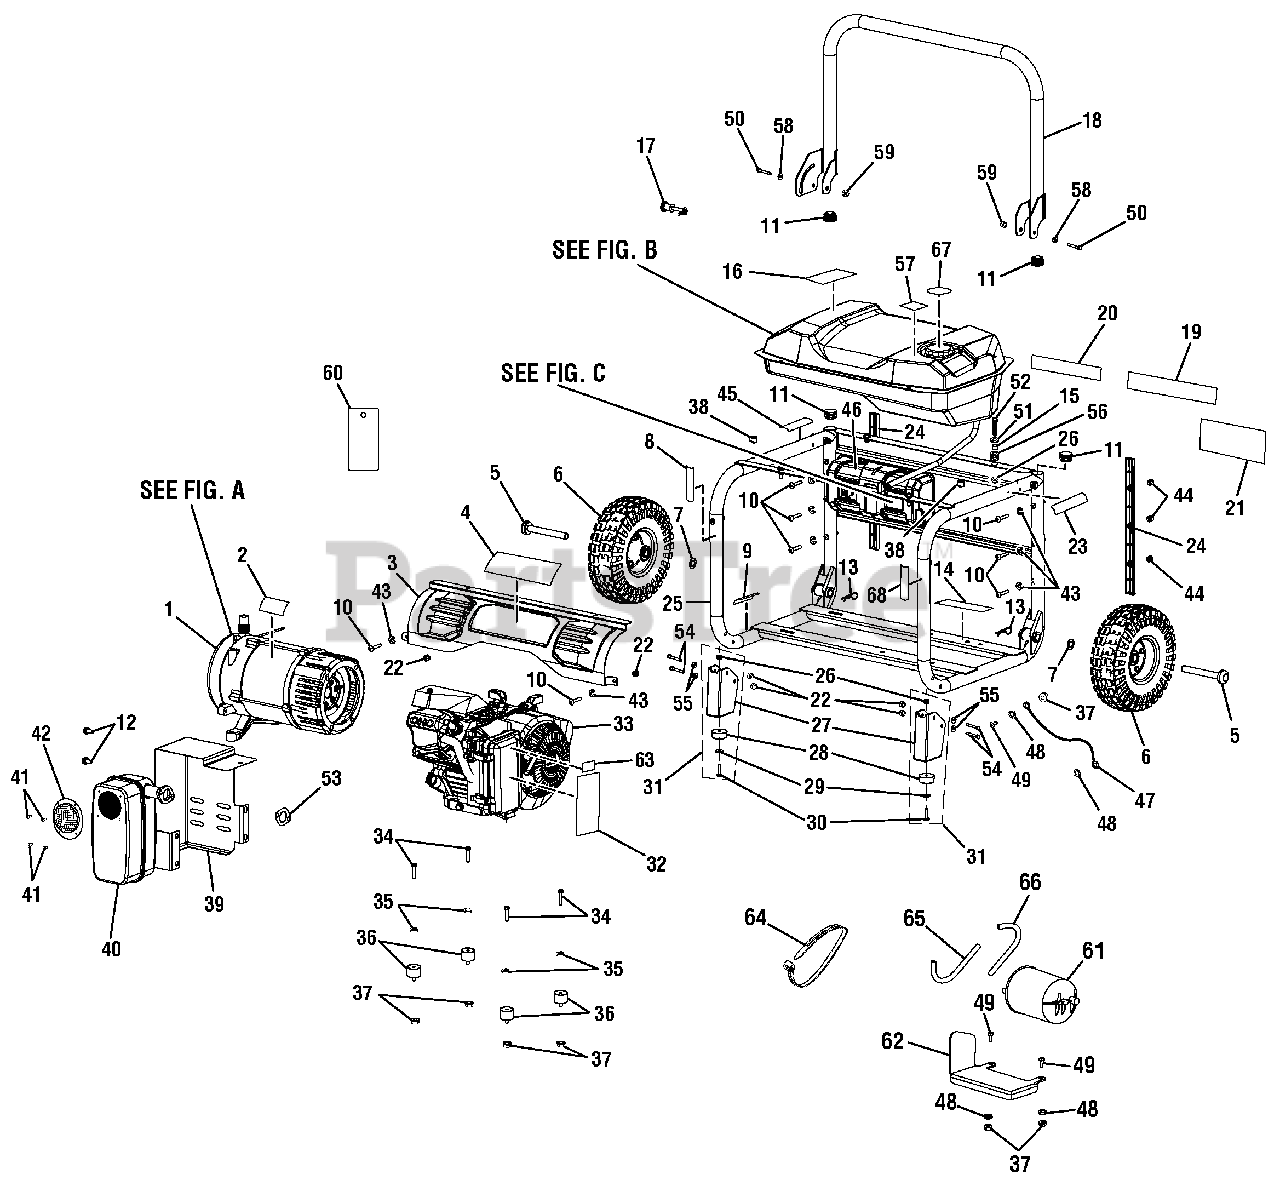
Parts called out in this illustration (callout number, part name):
1	GENERATOR HEAD ASSEMBLY
2	DATA LABEL
3	BACK PANEL ASSEMBLY
4	BACK PANEL LOGO LABEL
7	WASHER (5/8 IN.)
8	HOT SURFACE LABEL
9	COMBUSTION WARNING LABEL
10	BOLT(1/4-20 X 42.5 MM TORX HD)
11	END CAP
12	BOLT (5/16-24 X 5/8 IN.)
13	HITCH PIN
14	LUBRICANT LABEL
15	SPACER (FUEL TANK ISOLATOR)
16	CPSC LABEL
17	HANDLE RELEASE PIN ASSEMBLY
18	HANDLE ASSEMBLY
19	DANGER LABEL
20	GROUND WARNING LABEL
21	LOGO LABEL
22	LOCK NUT (1/4-20)
23	FIRE DANGER LABEL
24	FRAME SLIDE RAILS
25	FRAME ASSEMBLY
26	LOCK NUT (1/4-20)
28	WEAR PAD
29	WASHER (1/4 IN.)
30	BOLT (1/4-20 X 1 IN.)
31	FOOT ASSEMBLY
32	STARTING INSTRUCTION LABEL
33	Engine (Subaru EX30)(Parts available at your local Subaru dealer)
34	BOLT (5/16-18 X 1.5 IN)
35	LOCK WASHER (5/16)
36	ISOLATOR (GENERATOR)
37	HEX NUT (5/16-18 FLANGE HD.)
38	RUBBER HANDLE BUMPER
39	BACK MUFFLER COVER
40	MUFFLER (SUBARU EX30)
41	SCREW (8-32 X 3/8 IN.)
42	SPARK ARRESTOR
43	LOCK WASHER (M6)
44	HEX NUT (1/4-20)
45	PIN RELEASE LABEL
46	CONTROL PANEL
47	GROUND WIRE ASSEMBLY
48	STAR WASHER (5/16 IN.)
49	BOLT (5/16-18 X 3/4 IN.)
50	BOLT (M8 X 55 MM HEX HD.)
51	WASHER (1/4 IN.)
52	BOLT (1/4-20 X 1 IN.)
53	MUFFLER GASKET
54	BOLT 1/4-20 X 2 IN T30 TORX HD
55	WASHER (1/4 IN.)
56	ISOLATOR (FUEL TANK)
57	E85 LABEL
58	WASHER (3/8 IN.)
59	HEX NUT (M8)
60	DANGER HANG TAG
61	CANISTER
62	CANISTER BRACKET
63	CHOKE LABEL
64	CABLE TIE
65	PURGE HOSE
66	ROLLOVER VENT
67	FUEL STABILIZER LABEL
68	FIRE DISTANCE LABEL
